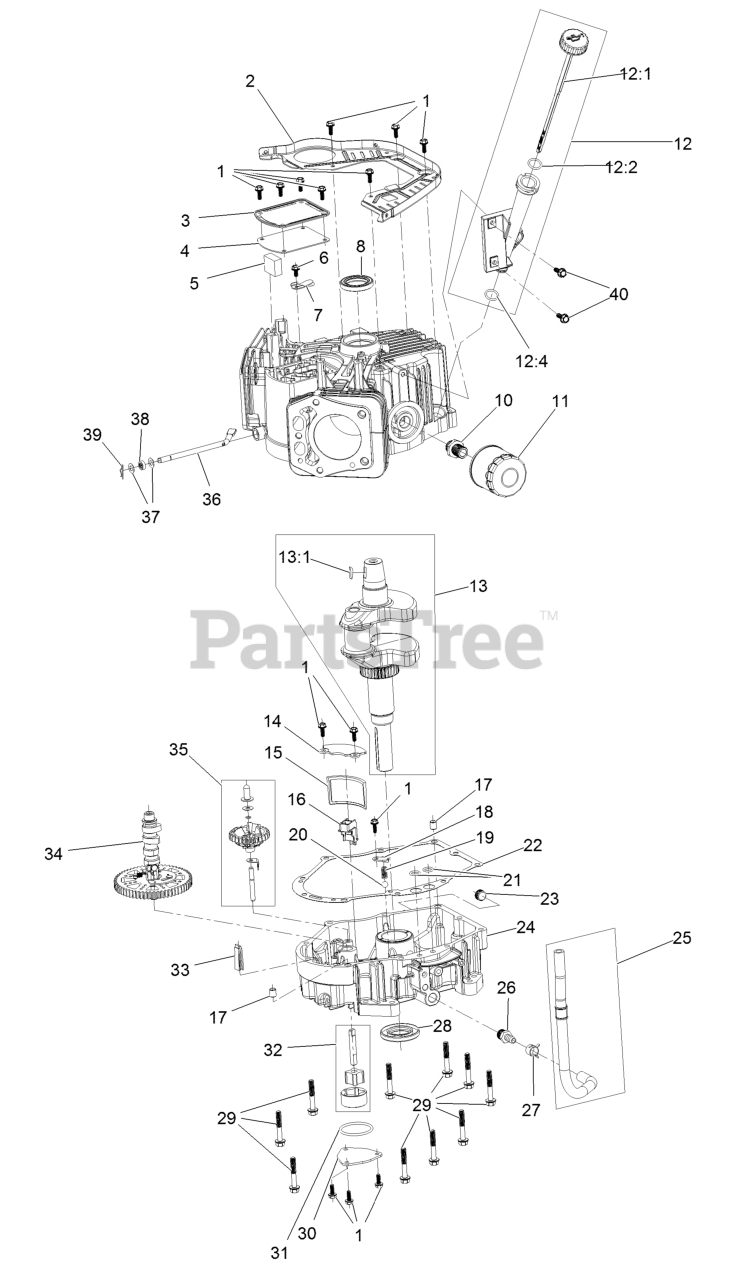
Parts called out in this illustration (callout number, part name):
1	Screw-HHF
3	Cover-Breather
4	Gasket-Breather
5	Filter-Breather
6	Screw-HHF
7	Valve-Breather
8	Seal-Oil
10	Adaptor-Filter, Oil
11	Filter-Oil
12	Oil Tube ASM
12:1	Dipstick
13	Crankshaft
13:1	Key-Woodruff
14	Cover-Screen, Oil
15	Screen-Oil
16	Retainer-Screen
17	Pin-Dowel
18	Plate-Retainer
20	Valve-Ball
22	Gasket-Cover, Crankcase
23	Plug-Drain
24	Cover-Crankcase
25	Oil Drain Hose ASM
26	Fitting-Hose
27	Clamp-Hose
29	Screw-HHF
30	Cover-Oil Pump
32	Oil Pump ASM
33	Deflector-Oil, Rubber
34	Camshaft
35	Governor ASM
36	Shaft-Governor
37	Washer-Plain
38	Seal-Oil
39	Pin-Hair
40	Screw-HHF
